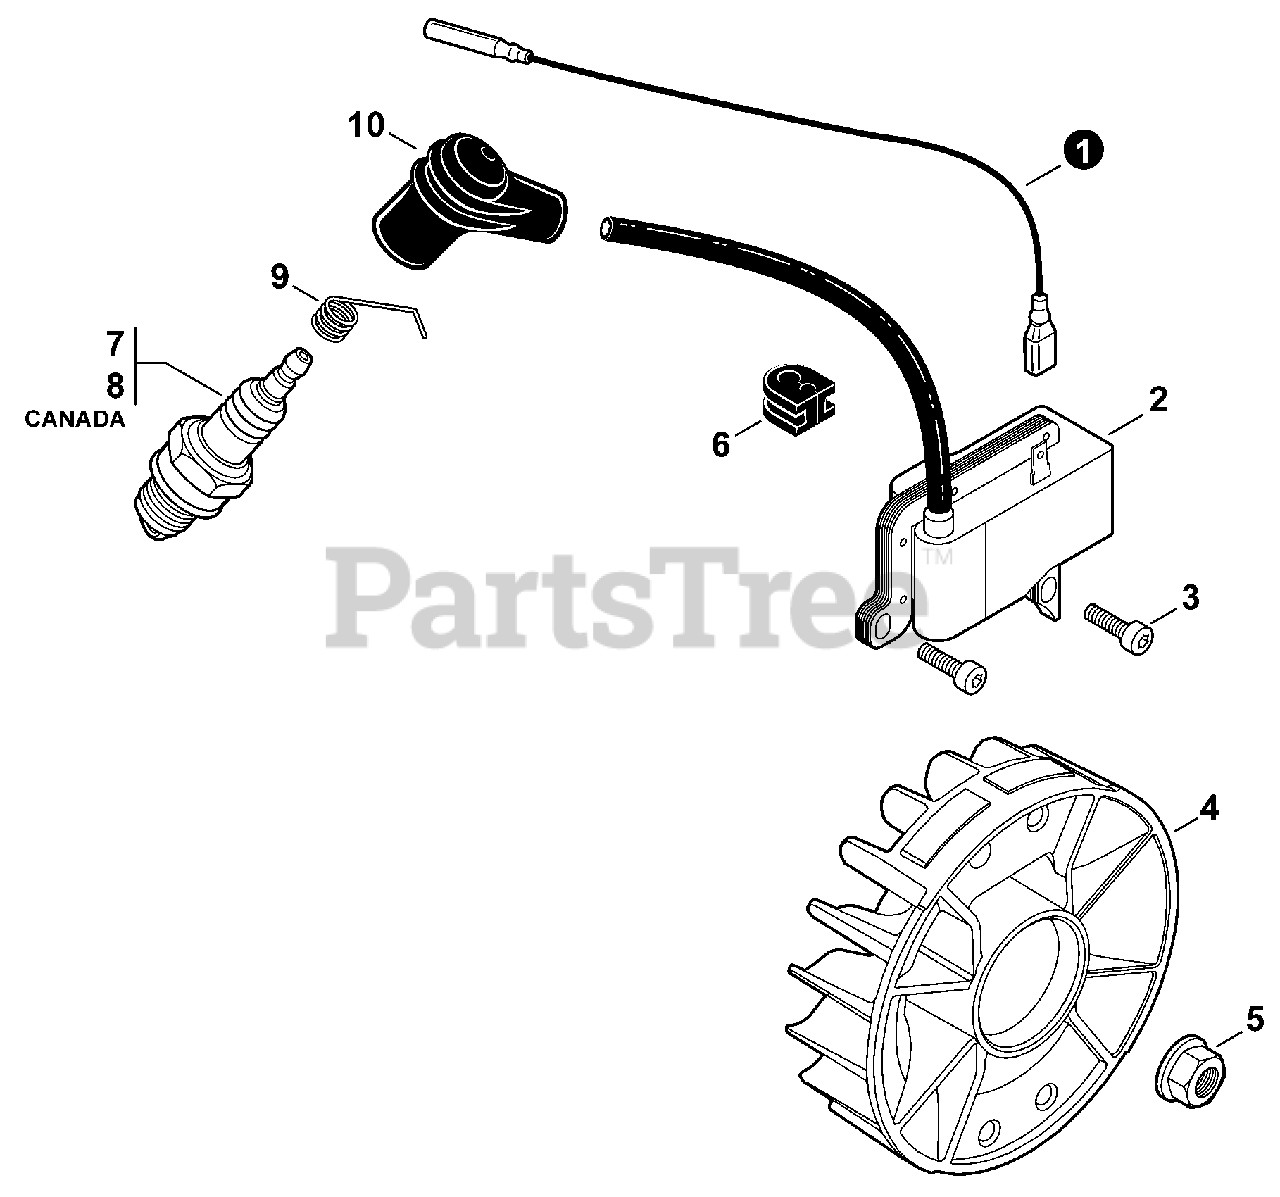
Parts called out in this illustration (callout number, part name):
1	LEAD L= 470
2	COIL, IGNITION
3	BOLT, TORX 5×20
4	FLYWHEEL
5	NUT, FLANGE 10×1.25
7	SPARK PLUG - BPM6Y
8	SPARK PLUG - BPMR6Y
9	TERMINAL, SPARK PLUG
10	CAP, SPARK PLUG
